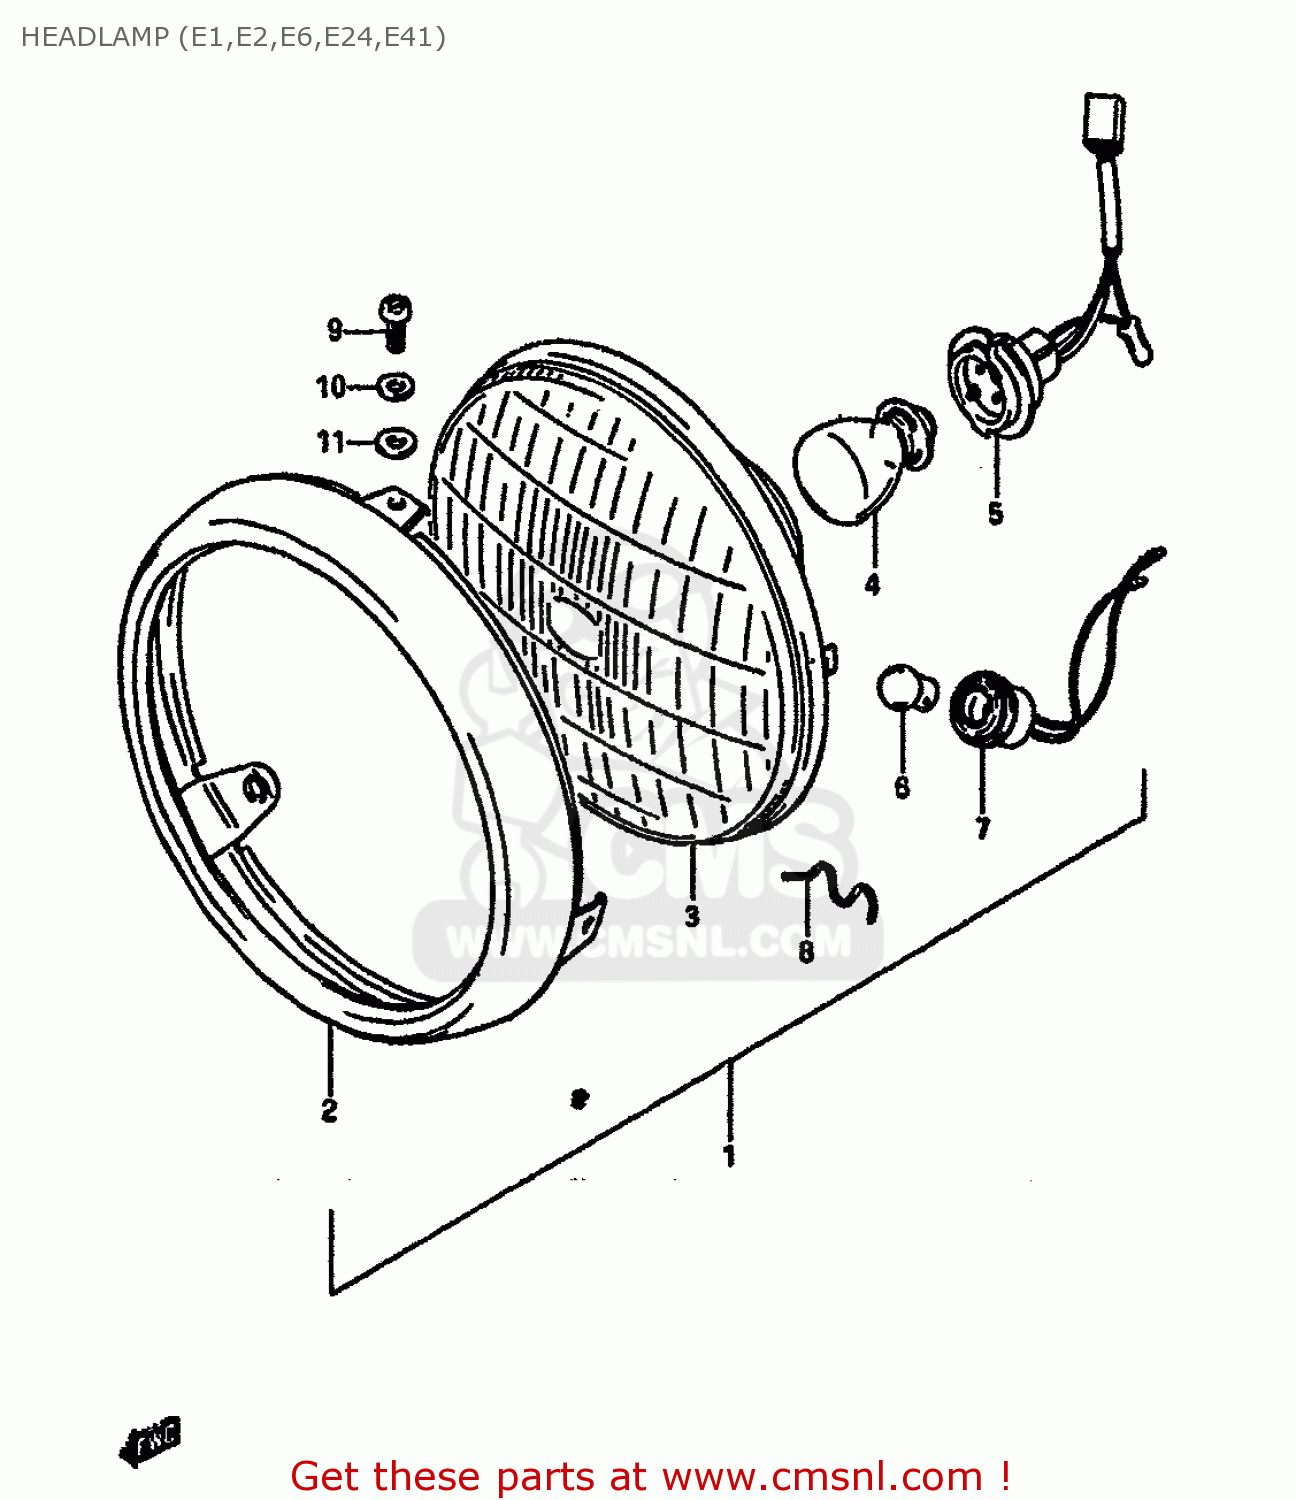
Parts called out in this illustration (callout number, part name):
1	HEADLAMP ASSY
2	RIM
3	UINT
4	BULB
5	SOCKET
6	BULB(6V/3W)
7	SOCKET
8	SPRING
9	SCREW
10	LOCK WASHER
11	WASHER
